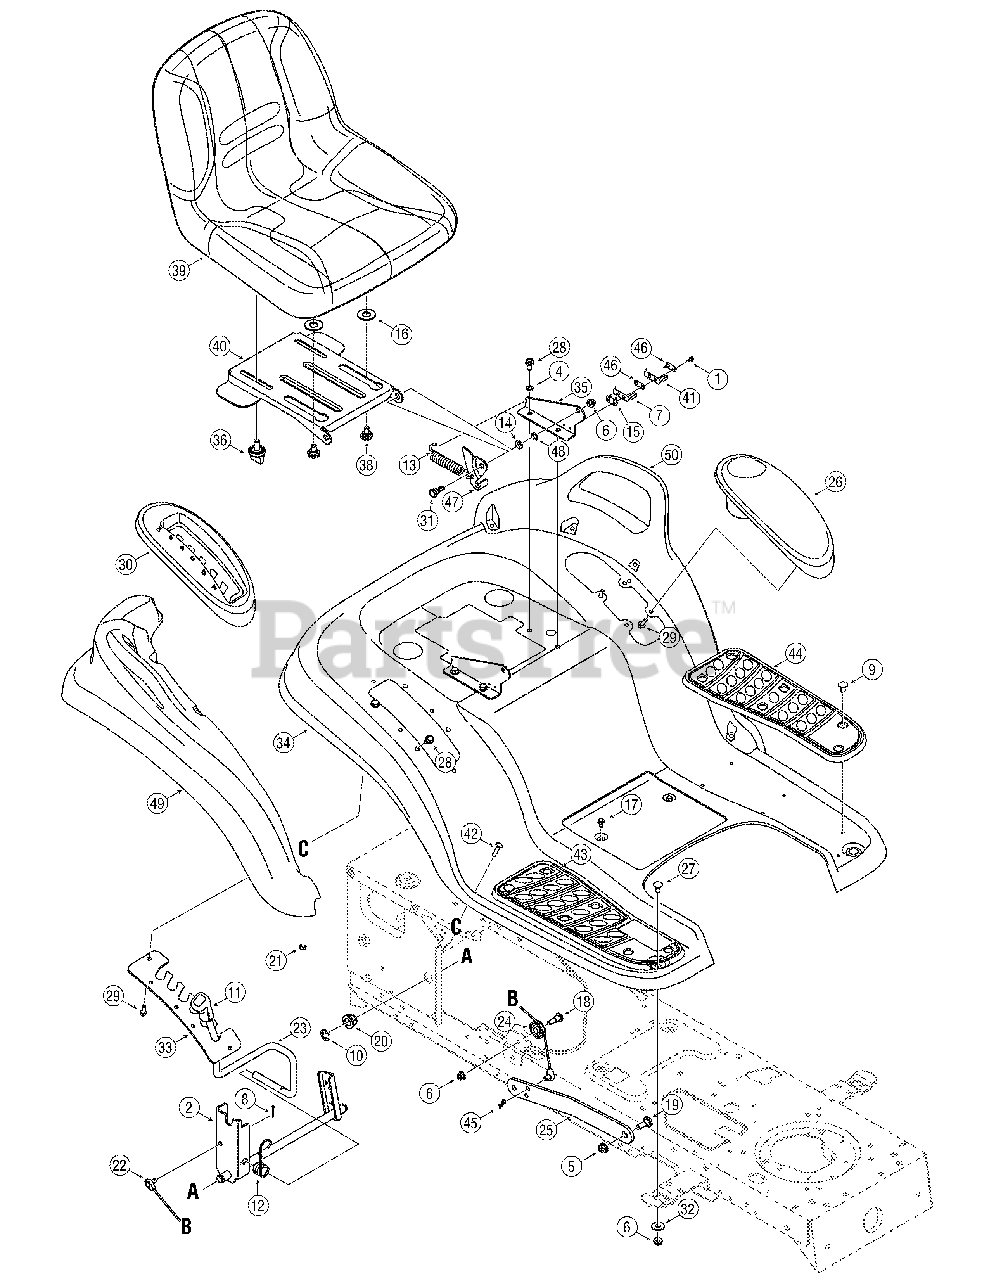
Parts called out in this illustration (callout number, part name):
1	Screw, #8-18 x.500
4	Lock Washer, 5/16
5	Flange Lock Nut, 3/8-16
6	Flange Lock Nut, 5/16-18
7	Inner Seat Spring Switch
8	Hairpin Clip
9	Foot Pad Clips
10	E-Ring
11	Handle Grip
12	Torsion Spring
13	Extension Spring,.84 x 4.6
14	Flat Washer
15	Insulator Boss Plate
16	Flat Washer, .406 x .875 x .059
17	Screw, 1/4-20 x.500
18	Hex Cap Screw, 5/16-18 x.62
19	Shoulder Screw, 3/8-16
20	Hex Flange Bearing
21	Sems Nut 1/4-20
22	Lift Cable, 16.16
23	Lift Handle
24	Roller Pulley
26	Cover w/ Cup Holder
27	Carriage Bolt, 5/16-18 x.750
28	Self-tapping Screw, 5/16-18 x.625
29	Self-tapping Screw, 1/4-15 x.75
30	Lift Lever Cover
31	Shoulder Screw,.437 x.286
32	Flat Washer,.349 x 1.0 x.063
36	Knob, 3/8-16 x .875
37	Flange Lock Nut, 1/4-20
38	Shoulder Screw, 3/8-16 .625 x .145
39	High Back Seat, Black
41	Outer Seat Spring Switch
42	Carriage Screw 1/4-20 x 1.00
43	RH Foot Pad
44	LH Foot Pad
45	Cotter Pin
46	Insulator Plate
47	Seat Lift Bracket
48	Speed Clip
49	RH Fender Flare
50	LH Fender Flare
